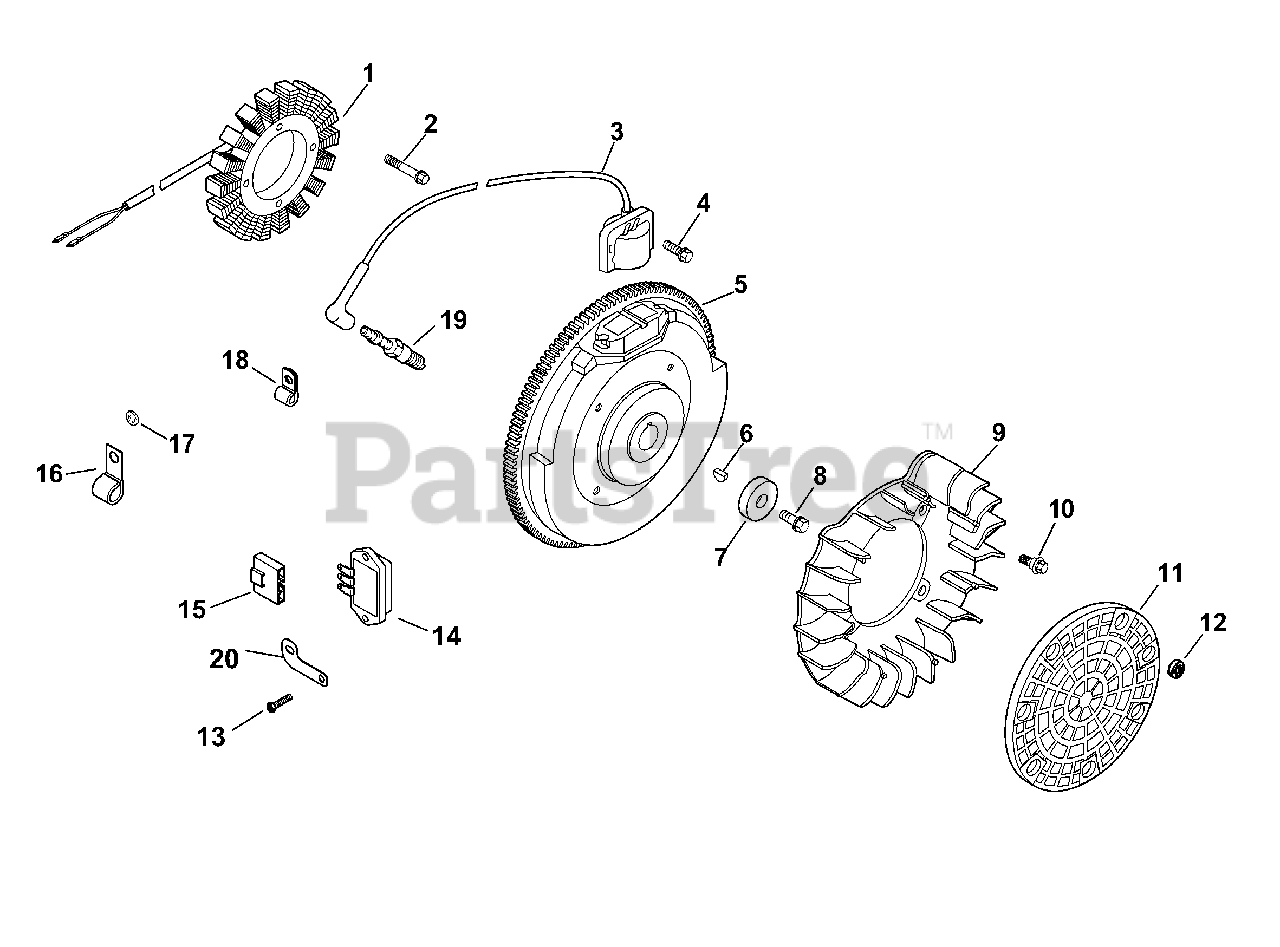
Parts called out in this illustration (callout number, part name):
1	Kit, 15 / 20 Amp Stator (Includes Terminal)
2	Screw, Thd Frm M5X0.8X25
3	Kit, Module Igntn (CDI Fixed)
4	Screw, Flg Thd Frm M5X.8X20
6	Key, 3/16" X 5/8"
7	Washer, Flat 13/32"
8	Screw, Flg M10X1.5X45 - (#25086361S)
9	Fan
10	Bolt, Shoulder
11	Screen, Grass Low Prfle w/o Hole
13	Screw, Hex Flange Hi-Lo
14	Regulator/Rectifier
16	Clip, Cable
17	Washer, Flat 1/4" (O.D. 1/2")
19	Spark Plug, RFI
20	Bracket, Ground Strap
